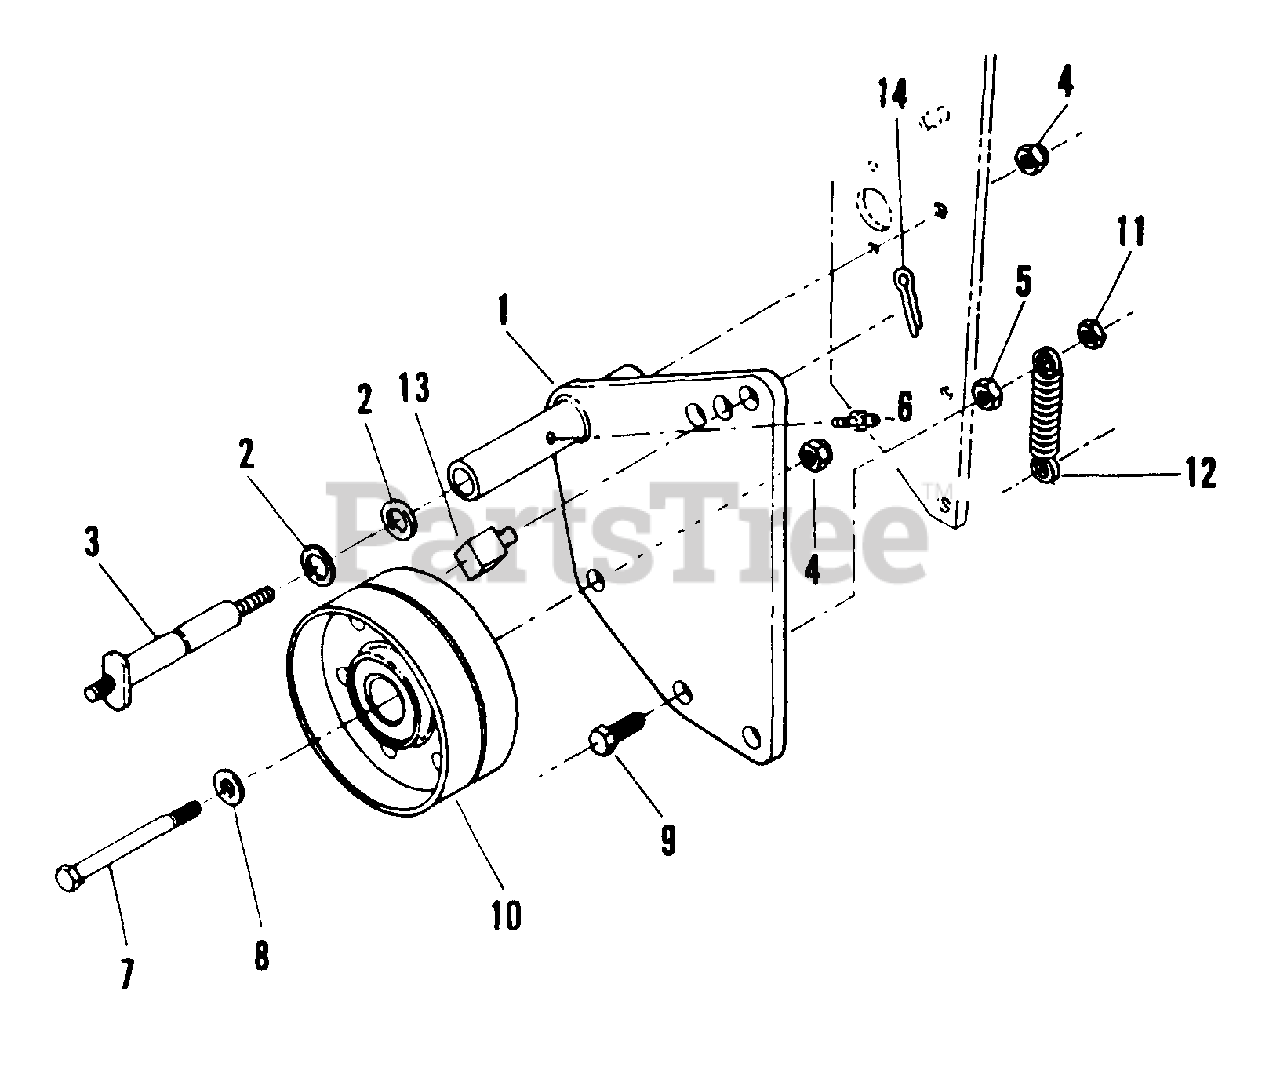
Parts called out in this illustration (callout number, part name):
1	ARM, Traction L.H.
2	MACHINE BUSHING, 5/8"
3	STUD, Fender Mount
4	NUT, 3/8" - 16 Nyloc
5	NUT, 5/16" Flange Lock
6	GREASE FITTING, 1/4" - 28 Str. Zerk
7	SCREW,3/8" - 16 x 2-1/4" Lg. Hex. Cap
8	FLATWASHER, 3/8"
9	BOLT, 5/16 - 18 x 1-1/4" Hex
10	PULLEY, Idler 4.0
11	NUT, 5/16"
12	SPRING, Traction
13	SWIVEL, Traction Rod
14	PIN, 3/32 x 1" Cotter
